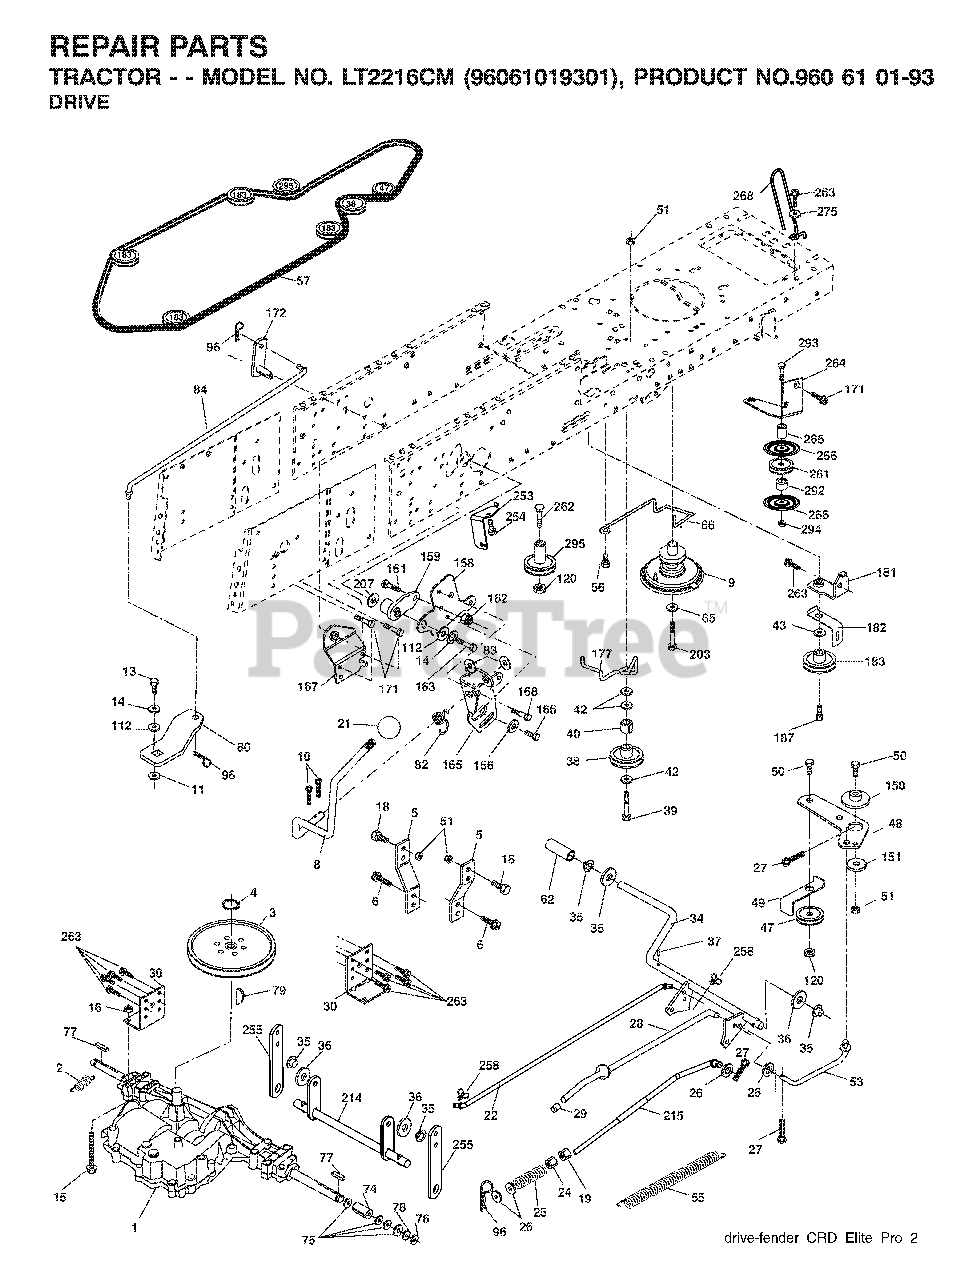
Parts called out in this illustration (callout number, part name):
2	SPRING,BRAKE RETURN
4	RETAINING RING LT
5	STRAP TORQUE
6	SCREW 5/16"
8	ROD SHIFT FENDER ADJUST LT
10	PIN COTTER
11	WASH-SHFT PLT LT
13	BOLT 1/4-28X3/4
14	LOCKWASHER
15	BOLT HEX 5/16-18 GR 5
16	NUT.71038.31-18.HEX.NYLOCK
19	NUT
21	KNOB.DUCKHEAD.1/2
24	NUT
25	SPRING ROD LT
27	COTTER PIN
28	ROD, PARKING BRAKE
29	PLUNGER CAP
30	BRKT, MOUNT TRNSAXLE
34	SHAFT, FOOT PEDAL
35	BEARING.NYLON
36	WASHER LT
37	DRIVE PIN
38	PULLEY.FLAT
42	WASHER
47	IDLER PULLEY
48	BELLCRANK, CLUTCH
49	RETAIN BELT
50	BOLT.3/8-16X1.50
51	LOCKNUT
53	LINK.CLUTCH.7.66.2005
55	SPRING, RETURN LT
56	SCREW.3/8-16
57	V-BELT.KEV.111"
62	PEDAL COVER T
65	LOCKWASHER
66	KEEPER BELT ENGINE
74	SPACER AXLE
76	E-RING LT
77	SQUARE KEY
80	ARM SHIFT
82	SHIFT SPRING
83	WASHER
96	RETAINER M
112	WASHER LT
120	NUT LOCK FLG 3/8-16 UNC
150	BUSHING.BELLCRANK.GRD.DR
151	WASHER 12/32X2X10GA
156	WASHER.SRRTD.5/16
158	BRACKET
159	HUB.SHIFT
161	BOLT
162	NUT.CROWNLOCK.1/4
165	RP BRACKET
167	BRACKET
168	BOLT.SHOULDER.5/16-18X
187	BOLT.5/16-18X1.25
207	WASHER NYL
254	SCREW 3/8-16X1
258	CLIP RETAINER
261	FLAT IDLER PULLEY
263	SCREW, 3/8-16X3/4
275	WASHER
294	NUT, HEX 3/8-16
295	PULLEY IDLER COMPOSITE
